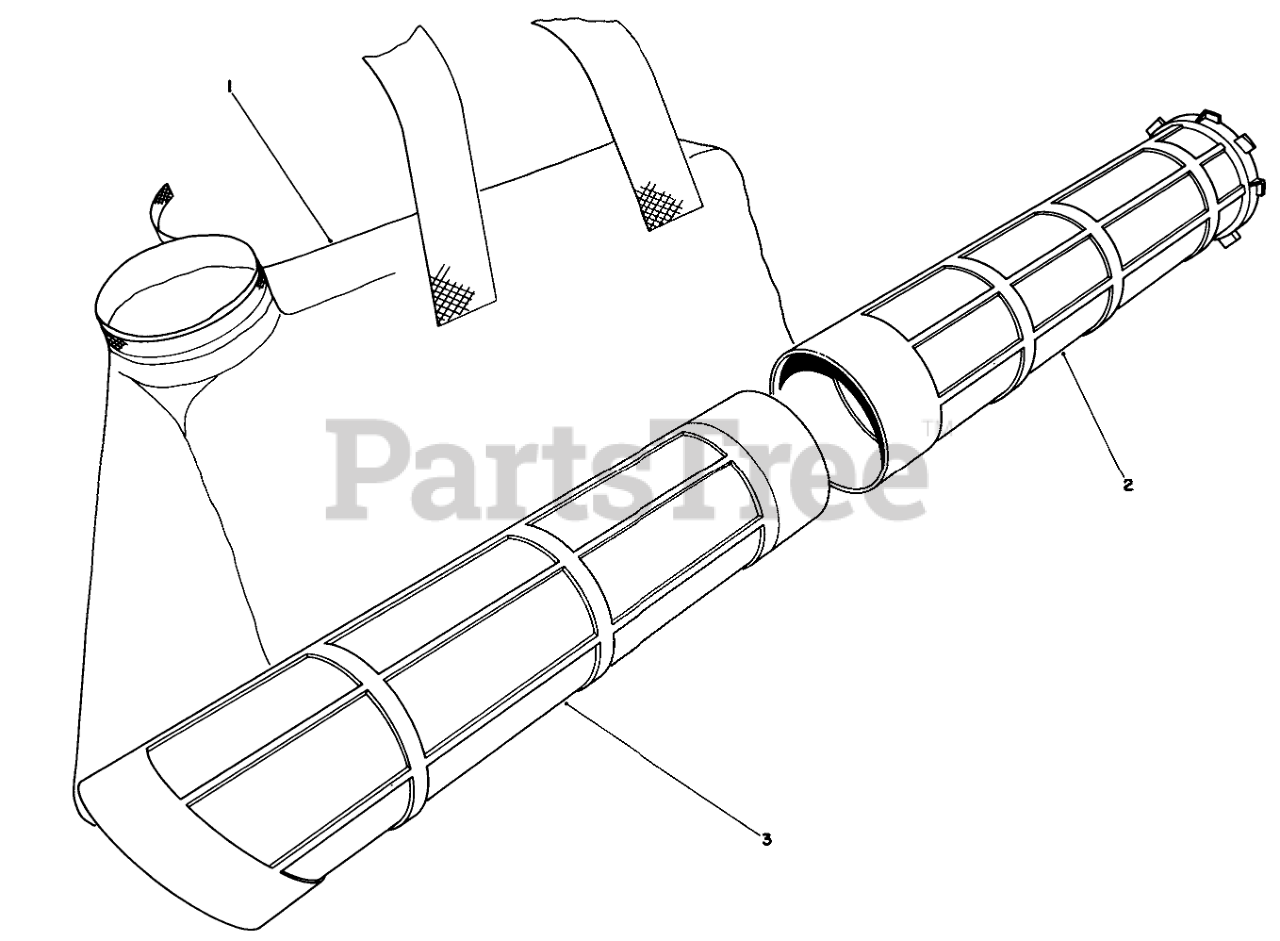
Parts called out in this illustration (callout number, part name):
1	Bag-Vacuum
2	Tube-Upper Vacuum
3	Tube-Lower Vacuum
